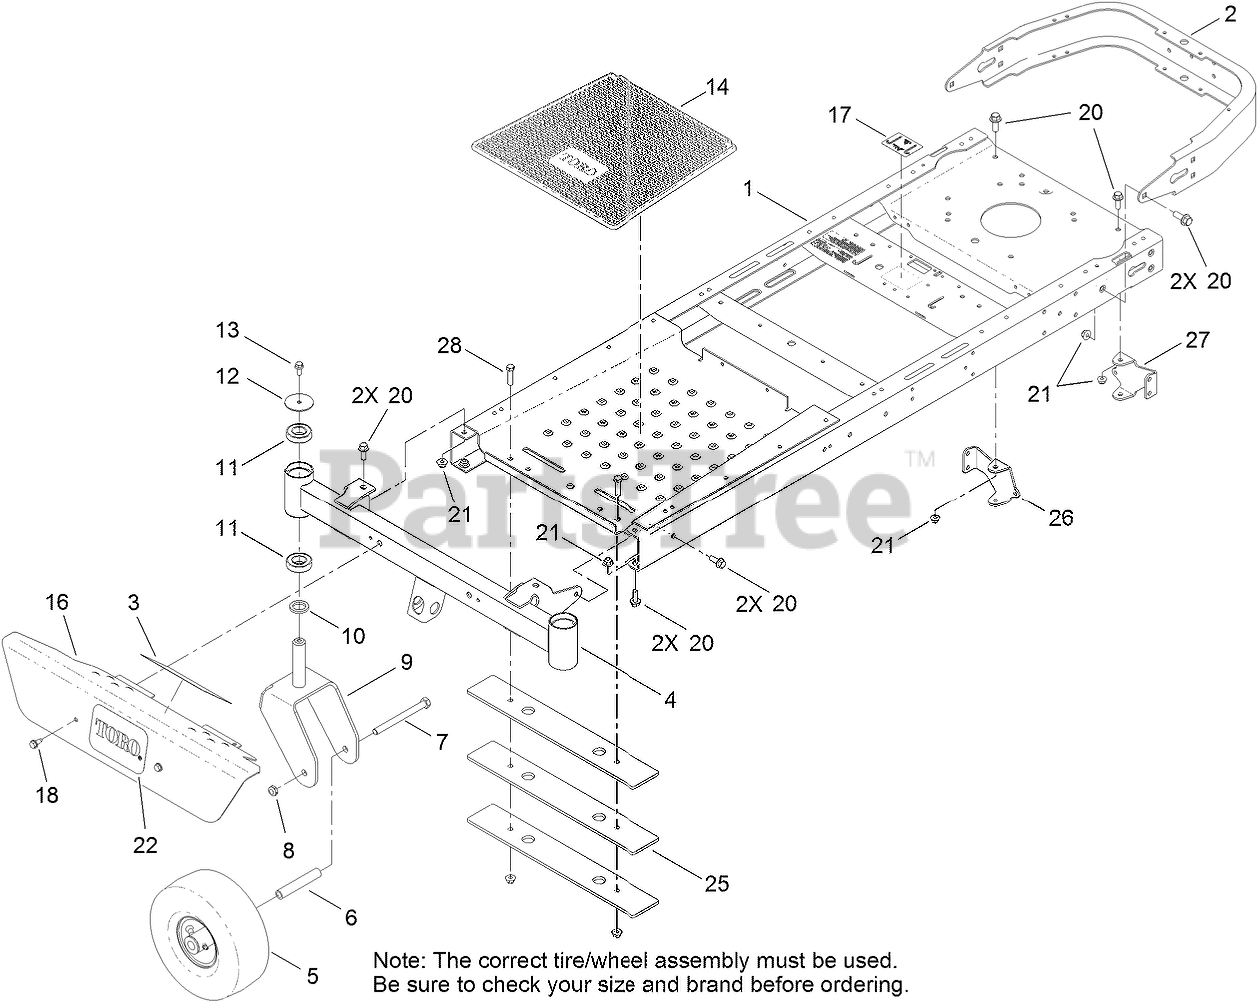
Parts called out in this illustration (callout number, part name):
1	FRAME ASM
2	BUMPER-REAR
3	DECAL-DANGER
4	AXLE-FRONT
5	CASTER WHEEL ASM (Kenda)
5	CASTER WHEEL ASM (CST)
6	BUSHING-SPANNER
7	SCREW-HH
8	NUT-LOCK, NI
9	FORK-CASTER
10	WASHER-THRUST
11	BEARING-BALL
12	WASHER
13	SCREW-HHF
14	MAT-FLOOR
16	FOOTREST
17	DECAL-TRANSPORT
18	SCREW-HWHTF
20	SCREW-HHF
21	NUT-HF, NI
25	PLATE-WEIGHT
26	MOUNT-HYDRO, REAR (RH)
27	MOUNT-HYDRO, REAR (LH)
28	SCREW-HH
